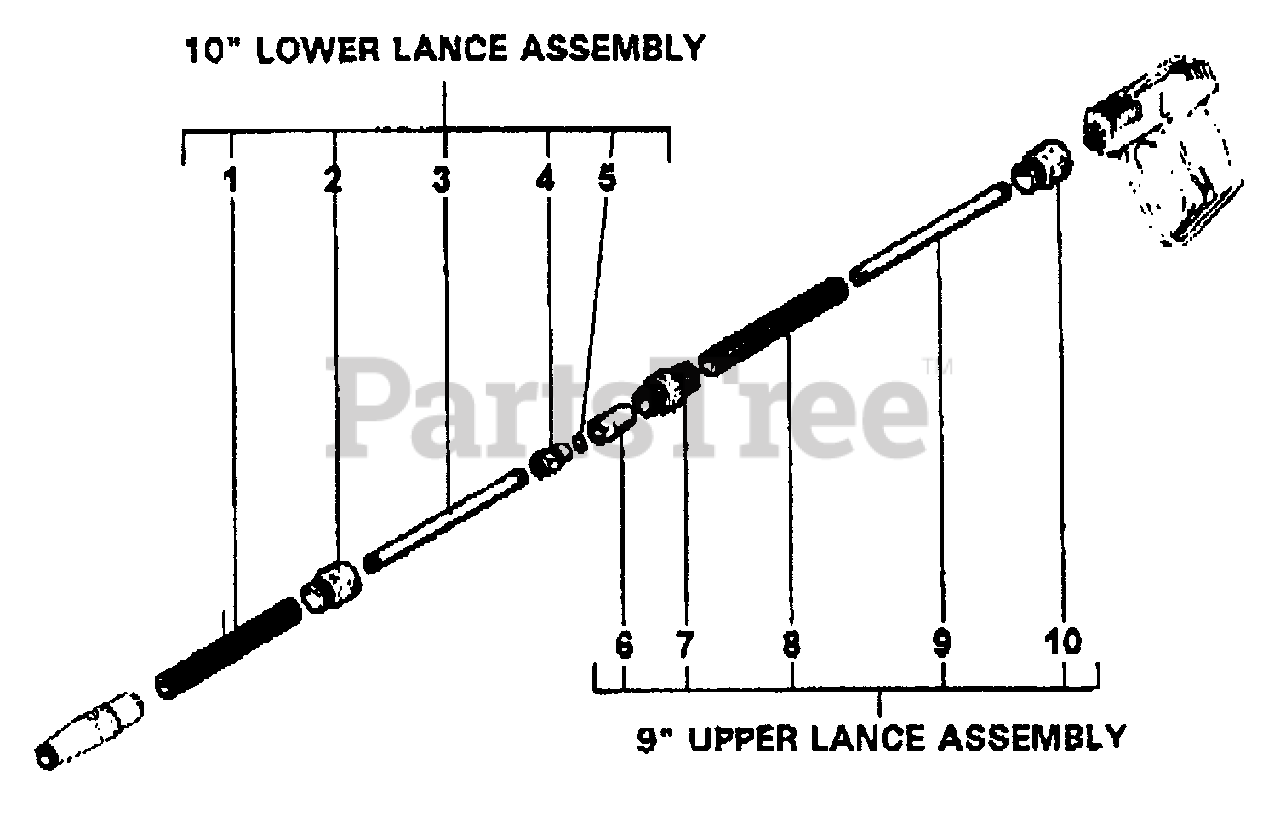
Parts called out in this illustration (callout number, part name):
1	GRIP, HANDLE
2	RINGNUT
3	TUBE
4	COUPLING - MALE
5	O-RING - .359 X .103
6	COUPLING - FEMALE
7	CONNECTOR
8	PROTECTOR, LANCE, FIX-UP
9	TUBE
10	CONNECTOR
